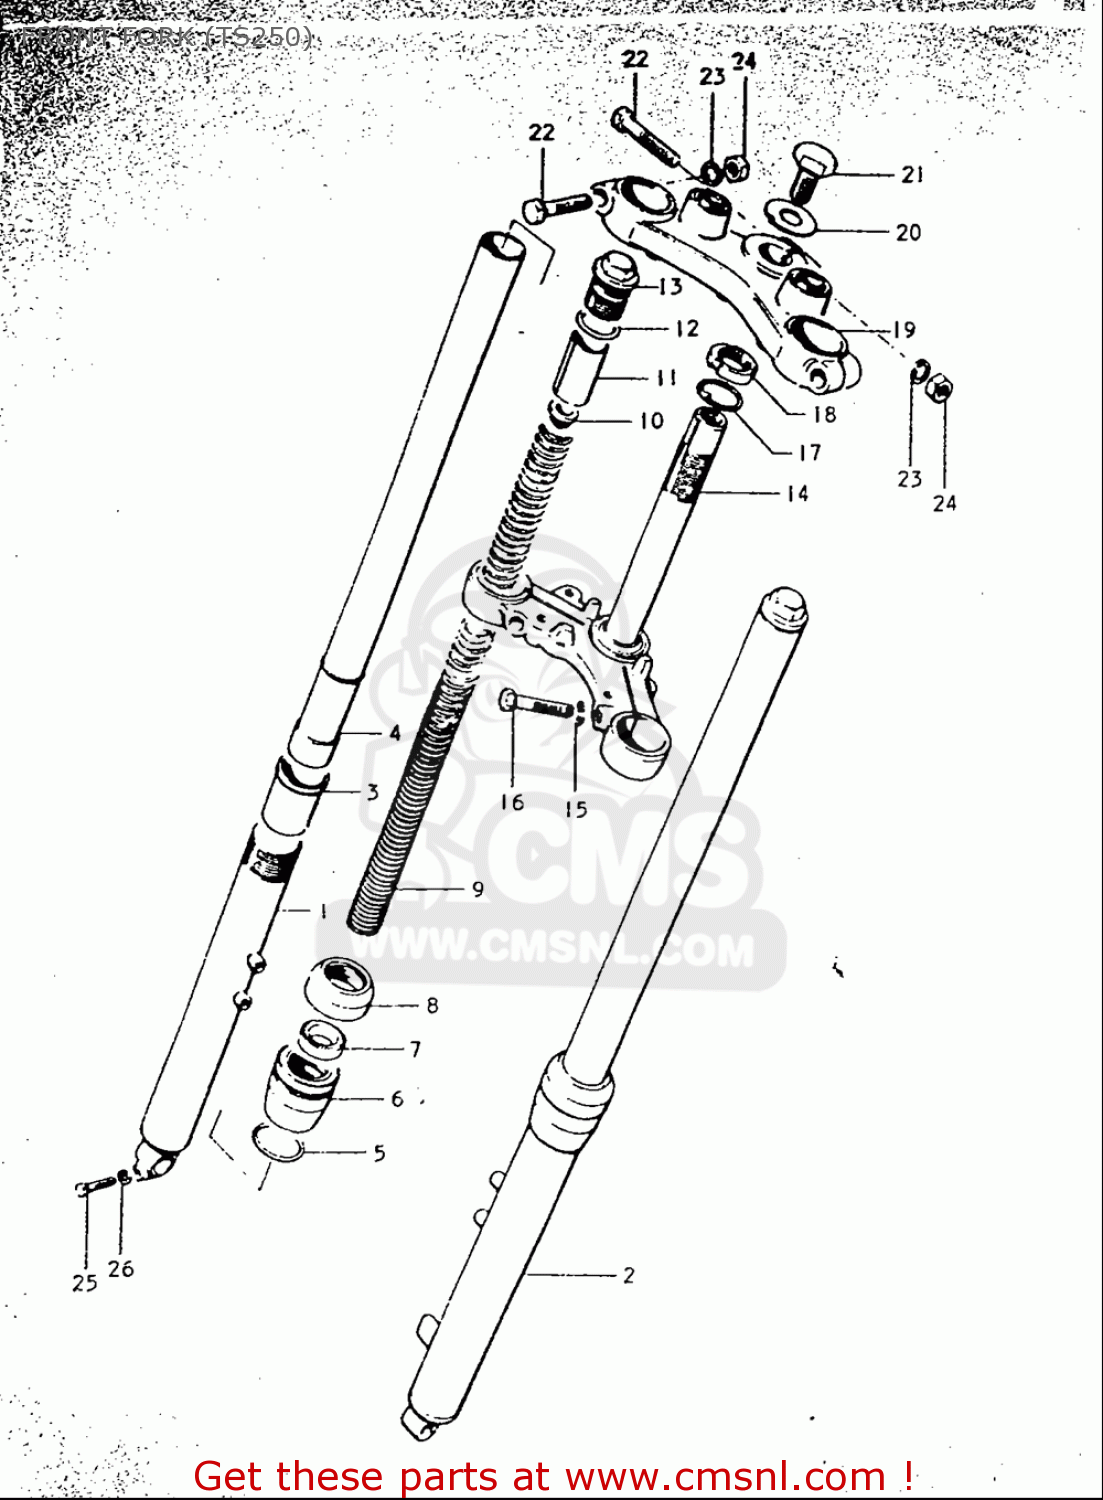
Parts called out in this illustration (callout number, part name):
6	OIL SEAL,FRONT FORK
7	OIL SEAL,FRONT FORK
12	O RING
15	WASHER,LOCK
23	WASHER,LOCK
26	WASHER,LOCK
